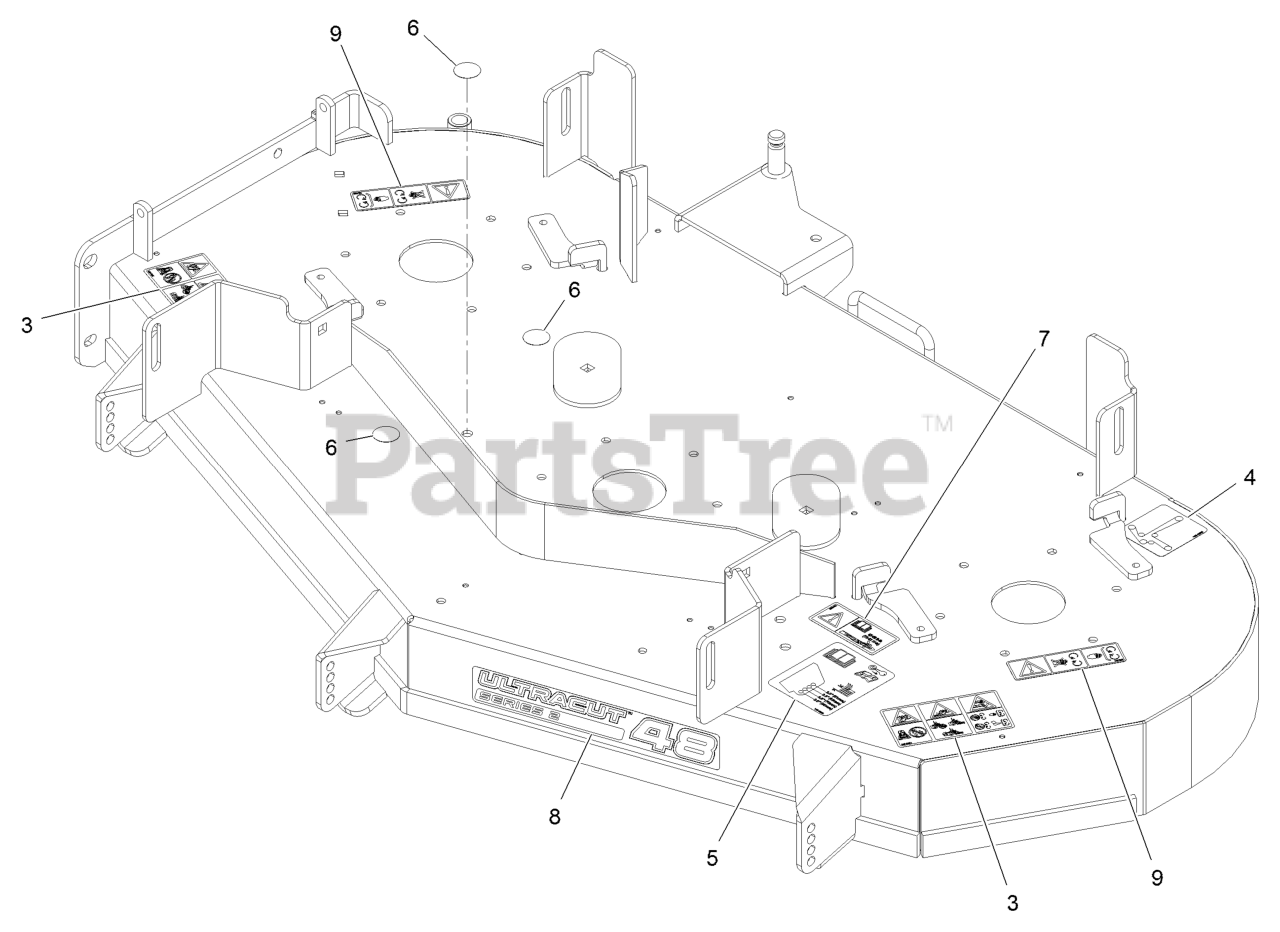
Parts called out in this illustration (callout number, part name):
3	DECAL-DANGER THROWN OBJECTS
4	DECAL-ROUTING, BELT
5	DECAL-ROLLER, ANTI-SCALP
6	DECAL-HOLE COVER
7	DECAL-BOLT TORQUE
8	Decal-Ultracut 48 Series 2
9	DECAL-COVER, MISSING
